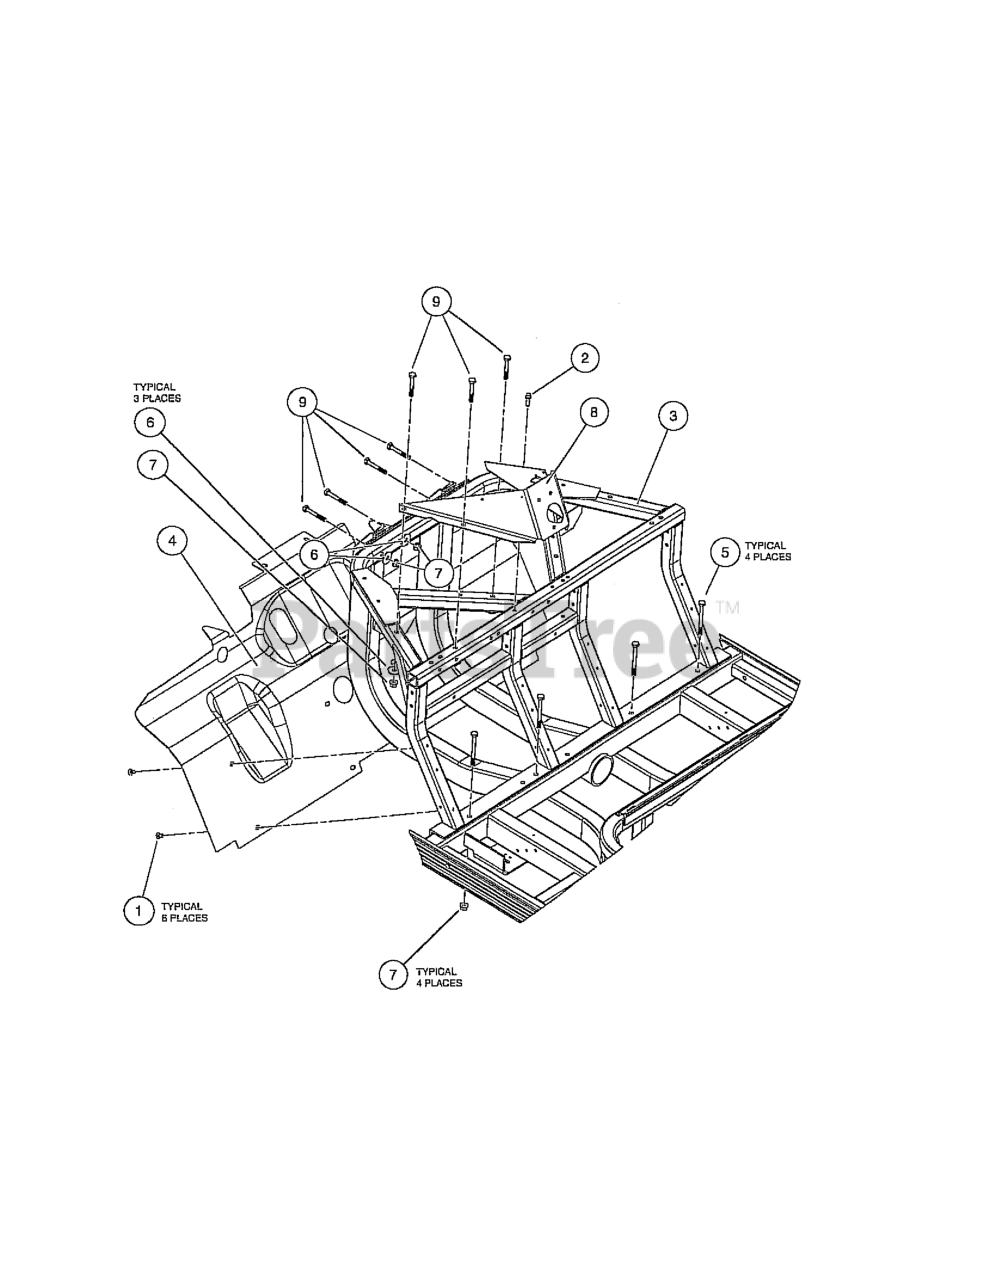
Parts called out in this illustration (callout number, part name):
1	BLIND RIVET, PUSH TYPE
2	SCREW-M8 X 1.25 30, TRI, HX F
4	GUARD, SPLASH
5	BOLT,M10X1.50X100 BLACK
6	WASHER HARD, M10
7	NUT FLG M10 X 1.5 MECH DEF
9	BOLT, M10 X 1.50 X 65
